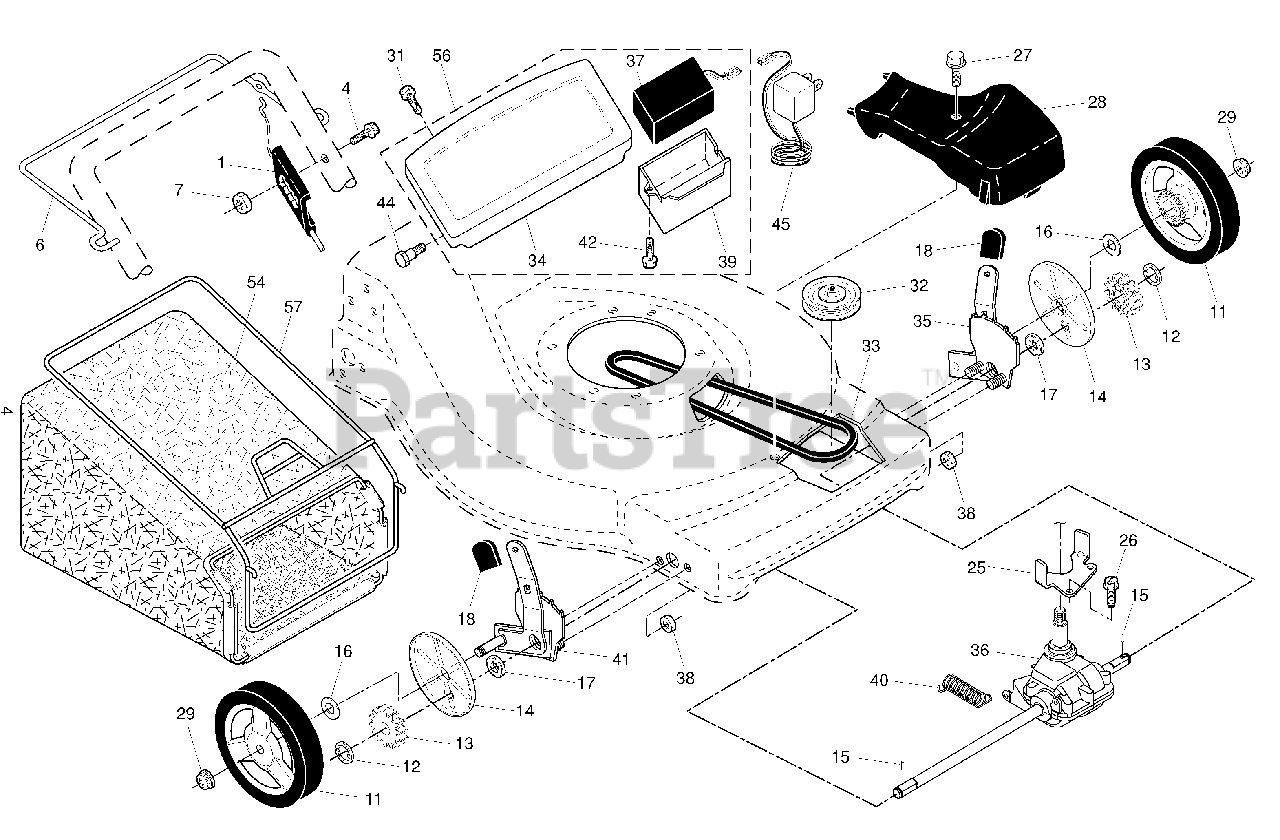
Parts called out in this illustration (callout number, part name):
1	Drive Control Cable
4	Screw 1/4-20
6	Bar, Drive Control
7	Nut, Hex 1/4-20
11	Wheel & Tire Assembly
13	Gear, Pinion
14	Dust Cover
15	Pawl, Drive
16	Washer, Flat 3/8
17	Ball Bearing
18	Selector Knob
25	Belt Keeper
27	Pan Head Tapping Screw #10-24 x 2-3/4
28	Drive Cover
29	Locknut, Hex
31	Screw, Torx Pan Head #20
32	Pulley, Drive
35	Kit, Wheel Adjuster, LH
36	Gear Case Assembly, Complete
37	Battery
38	Locknut, Hex 1/4-20
39	Box, Battery
41	Kit, Wheel Adjuster, RH
42	Screw, Hex Head #13 x 1/2
44	Screw, Shoulder, Hex Head #10-28 x 5/8
45	Charger, Battery
54	Grassbag Assembly
56	Trimplate / Battery / Battery Box Assembly
57	Frame, Grassbag
